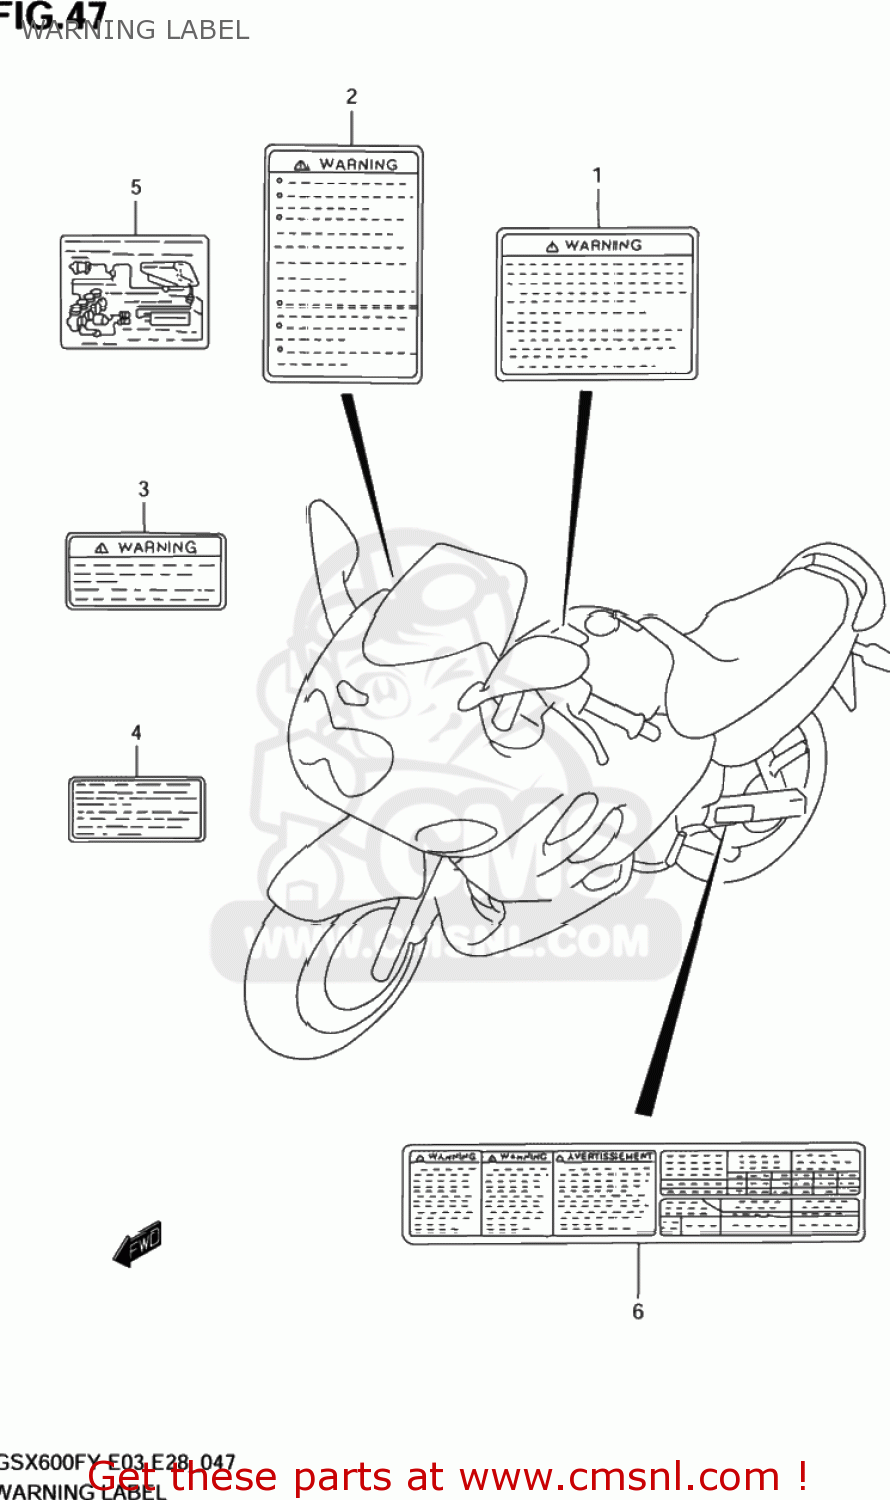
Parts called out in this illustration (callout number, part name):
1	LABEL,GENERAL WARNING
2	LABEL,SCREEN
3	LABEL,WARNING STEERING
4	LABEL,MANUAL NOTICE
5	LABEL,VACUUM HOSE ROUTING
6	LABEL,TIRE INFORMATION
7	MANUAL,OWNER'S
